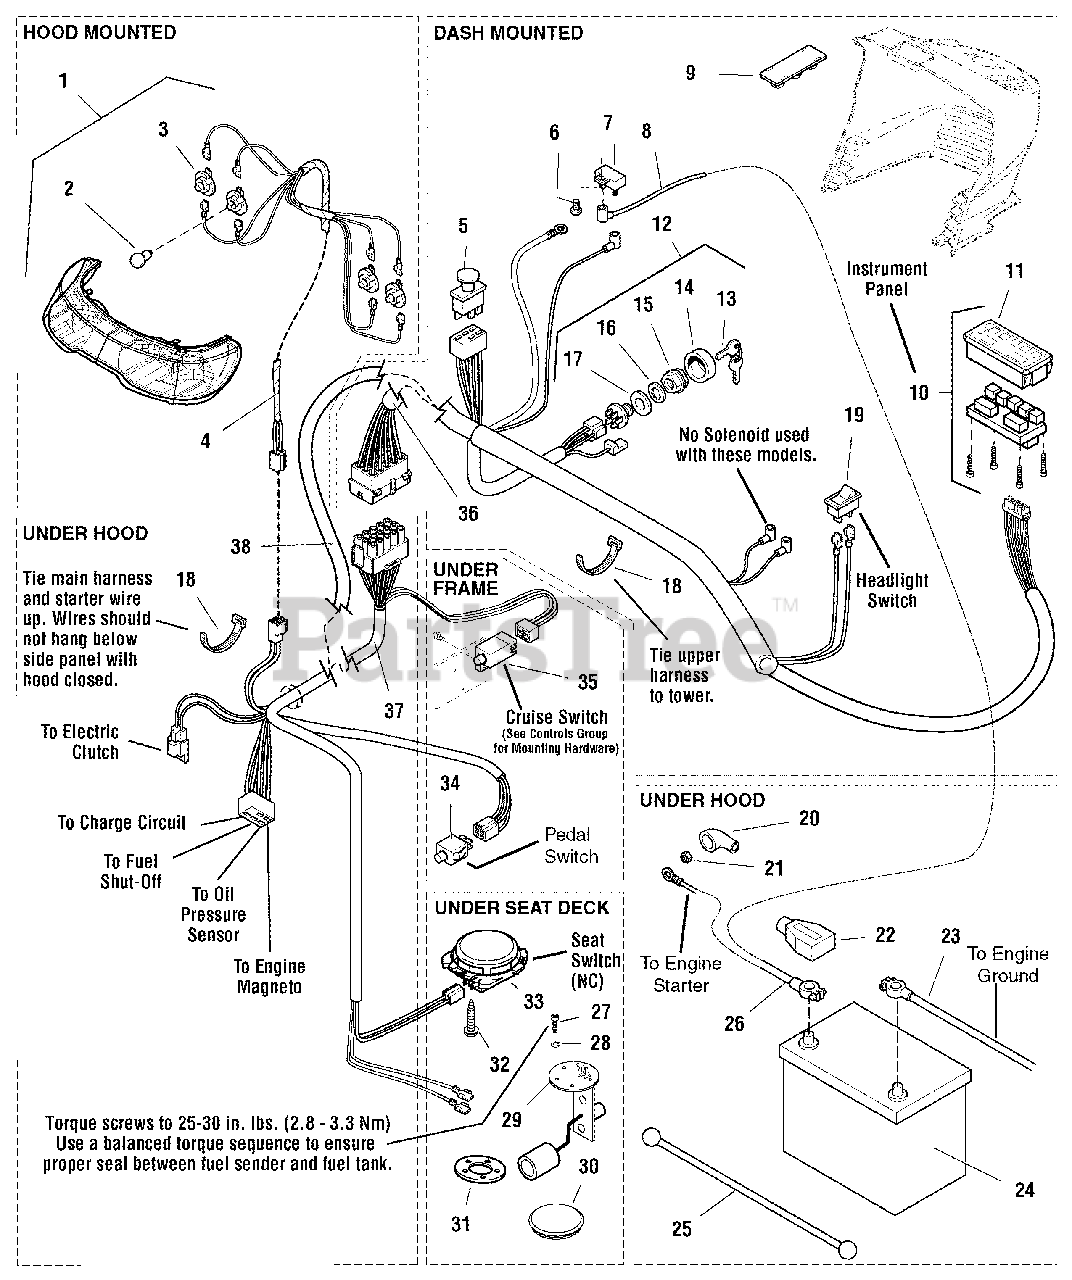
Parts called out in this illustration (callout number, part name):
1	HEADLIGHT ASSEMBLY, 4 Bulb, (Includes Ref. Nos. 2 & 3)
2	BULB, Headlight, 12.8V
3	SOCKET ASSEMBLY, Headlight, Sealed
4	HARNESS, Headlight
5	SWITCH, PTO, Push/Pull Symbols
6	CAPSCREW, Hex Washer Head Taptite, 1/4-20 x 1/2, Black
7	BREAKER, Circuit, 12 Volt 20 Amps
8	WIRE, 12GA 5.9" Long, Red
9	PLUG, Hole, Square
10	PANEL, Instrument with Fuel Gauge & Hour Meter (Includes Ref. No. 11)
11	COVER, Instrument Panel
12	SWITCH ASSEMBLY, Ignition, 6 Pin INDAK, (Includes Ref. Nos. 13, 14, 15, 16 & 17)
13	KEYS, Set of 2
14	COVER, For Ignition Switch, Plastic
15	NUT, Hex Flange, 5/8-32, Ignition Switch
16	LOCKWASHER, Internal Tooth, 5/8, Thin
17	WASHER, Shim
18	TIE, Self Locking
19	SWITCH, Headlights , 2 Terminal
20	BOOT, Insulator Cable Terminal, Red
21	NUT, Hex Flange M08-1.25
22	BOOT, Insulator Battery Terminal
23	CABLE, #6 x 26" Long, Ring Terminal
24	BATTERY, 12 Volt 500 CCA
25	STRAP, Battery, 14" Long, Rubber
26	CABLE, #4 26"
27	SCREW, Truss Head Phillips, #10-32 x 1/2
28	LOCKWASHER, Spring #10
29	SENDER, Fuel Tank
30	PLUG, Hole 3", Round
32	CAPSCREW, Hex Washer Head Plastite, 1/4 x 1/2
33	SWITCH, Seat
34	SWITCH, Push Button, Foot Pedal
35	SWITCH, Cruise Control
36	HARNESS, Wiring Upper
37	HARNESS, Wiring Lower (Models with 2 Piece Harness)
38	HARNESS, Wiring (Models with 1 Piece Harness)
